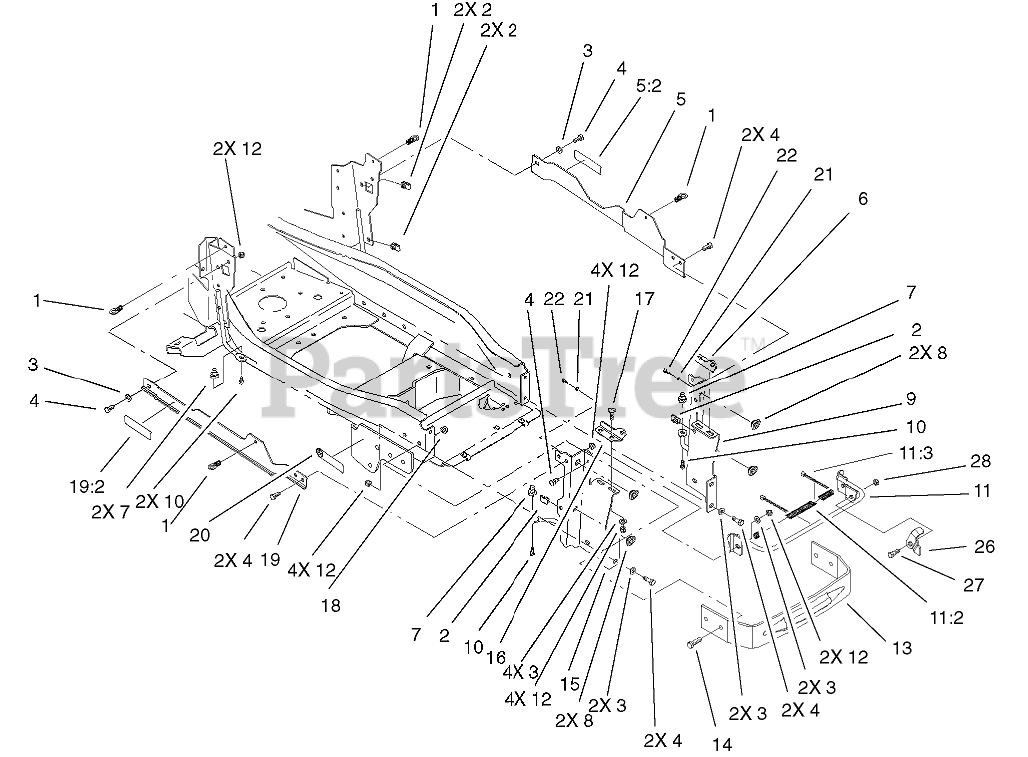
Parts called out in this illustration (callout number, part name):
1	LATCH ASM
3	WASHER-PLAIN
4	SCREW-HH
5	Support ASM (only on: 73471, 73542)
5	Support ASM (only on: 73570)
5:2	Decal-Warning (only on: 73570)
5:2	Decal-Warning (only on: 73471, 73542)
6	BRACKET-HINGE, LOWER LH
7	MOUNT-SIDEPANEL
8	GROMMET
9	SUPPORT-HOOD, LH
10	SCREW-PLASTITE
11	SUPPORT-HOOD
11:2	COVER-BRACE
11:3	TIE-CABLE
12	NUT-LOCK, NI
13	BUMPER-FRAME
14	SCREW-HH
15	SUPPORT-HOOD, RH
16	BRACKET-HINGE, LOWER RH
17	SCREW-CARR
18	NUT-LOCK, NI
19	Support ASM (only on: 73471, 73542)
19	Support ASM (only on: 73570)
19:2	Decal-Warning (only on: 73570)
19:2	Decal-Warning (only on: 73471, 73542)
20	DECAL-ATTACH A-MATIC
21	Washer-Flat (only on: 73570)
22	Screw-Selftap (only on: 73570)
26	LEVER-PROP, HOOD
27	BOLT-SHOULDER
28	NUT-LOCK, NI
